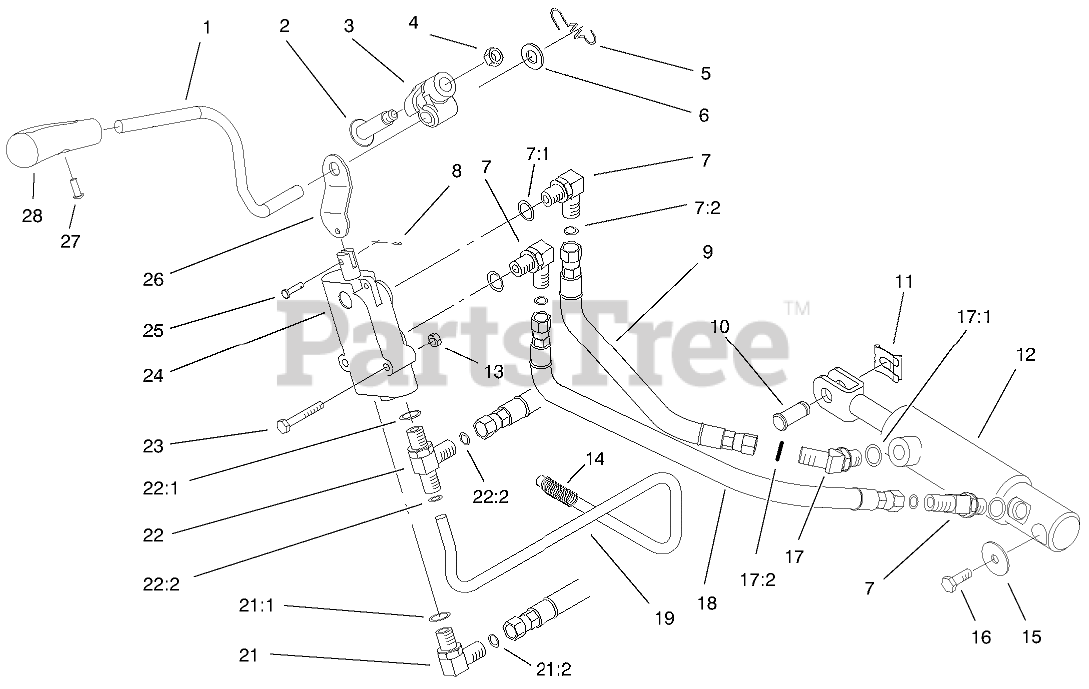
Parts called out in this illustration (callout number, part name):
1	HANDLE-LIFT
2	BOLT-SHOULDER
3	TRUNNION-LEVER, LIFT
4	NUT-JAM, LOCKING
5	SPRING-EXTENSION, LIFT
6	WASHER
7	FITTING-HYD, 90 DEGREE
7:1	O-RING
7:2	O-RING
8	PIN-COTTER
9	HOSE ASM
10	PIN-CLEVIS
11	CLIP-PIN
12	LIFT CYLINDER ASM
13	NUT-LOCK, NI
14	COVER-BRACE
15	WASHER-FLAT
16	SCREW-THREAD LOCKING
17	FITTING-HYD, 45 DEGREE
17:1	O-RING
17:2	O-RING
18	HOSE ASM
19	TUBE-HYD
21	FITTING-HYD, 90 DEGREE
21:1	O-RING
21:2	O-RING
22	FITTING-HYD, TEE
22:1	O-RING
22:2	O-RING
23	SCREW-HH
24	VALVE-HYD
25	PIN-CLEVIS
26	LINK-LIFT
27	SCREW-PPHTF
28	Knob-Lift (Only On: 73545)
28	Knob-Lift (Only On: 73546)
